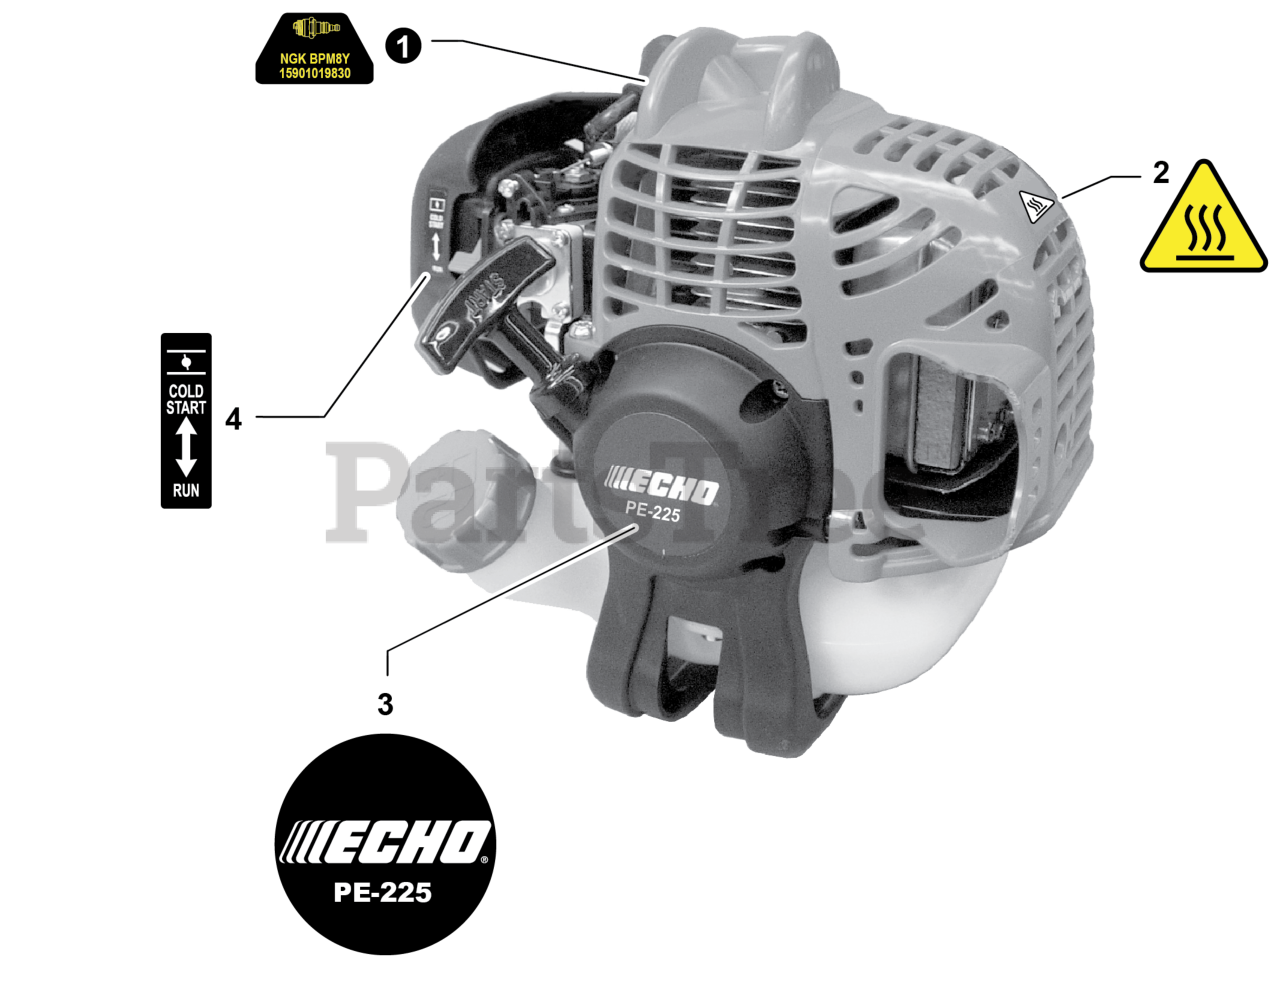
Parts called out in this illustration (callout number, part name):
1	LABEL - SPARK PLUG - BPM8Y
2	LABEL - CAUTION - HOT
3	LABEL - MODEL - PE-225
4	LABEL - CHOKE
